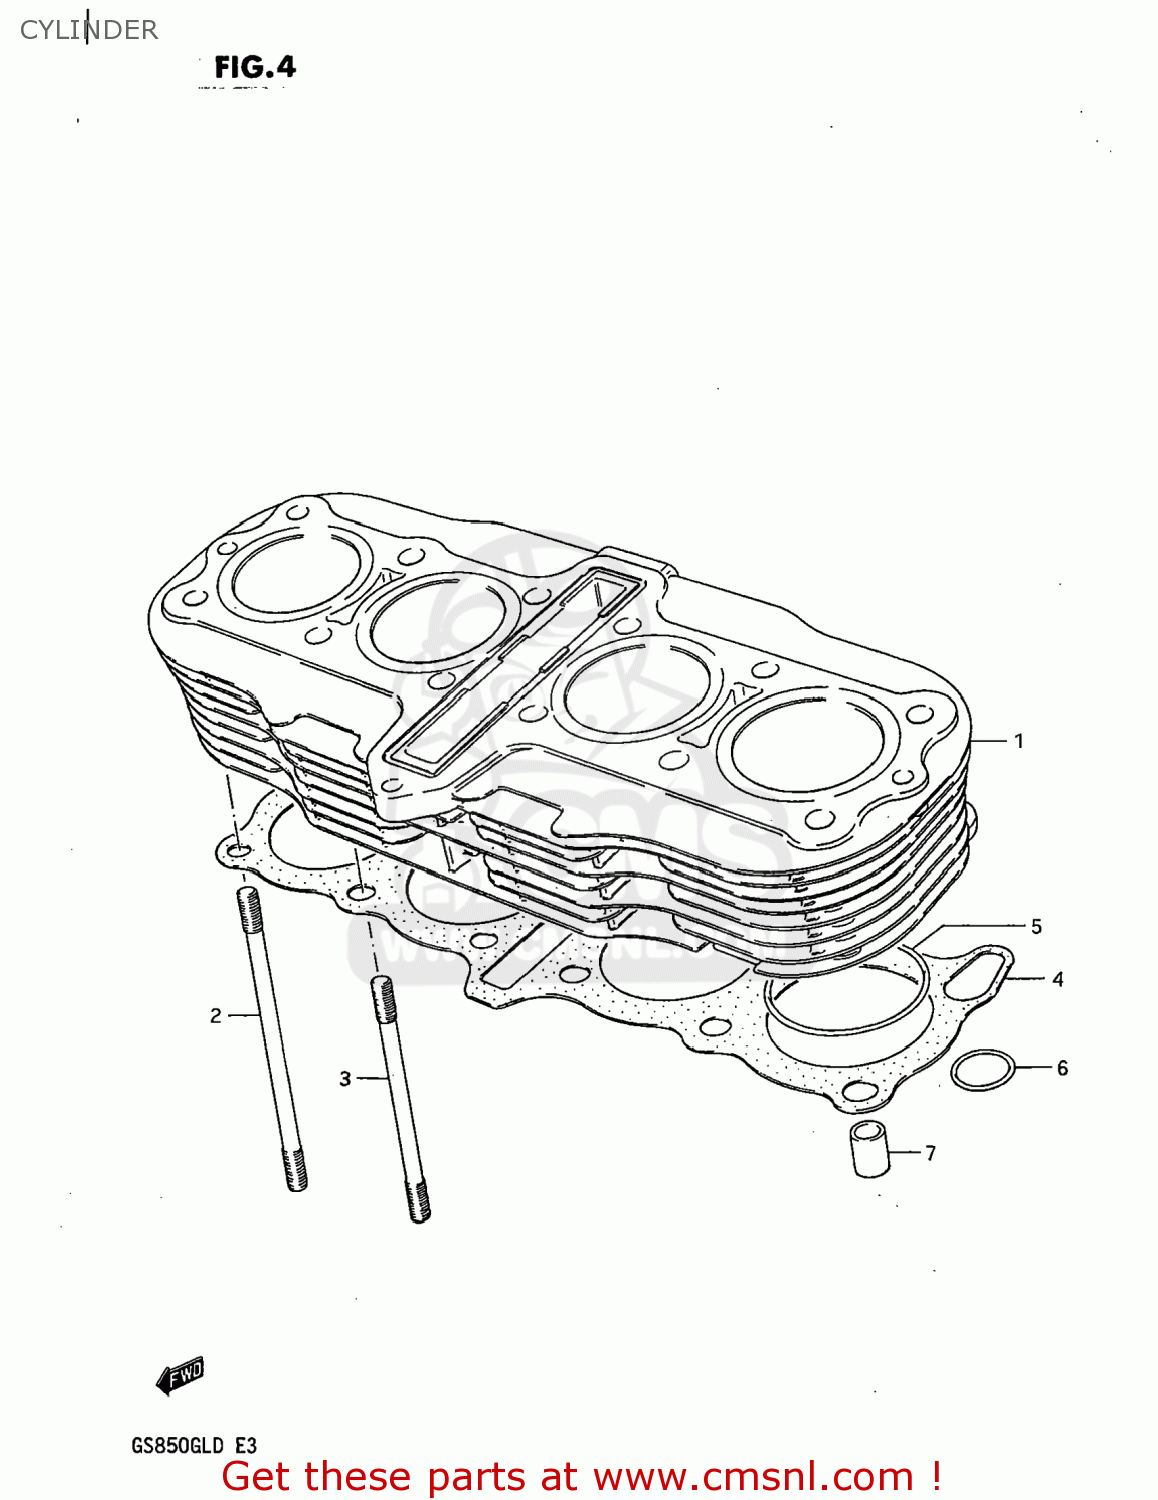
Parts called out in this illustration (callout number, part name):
1	CYLINDER
2	BOLT,STUD
3	STUD
4	GASKET,CYLINDER (MCA)
5	O RING(D:2,ID:70)
6	O RING(D:3.05)
7	PIN
